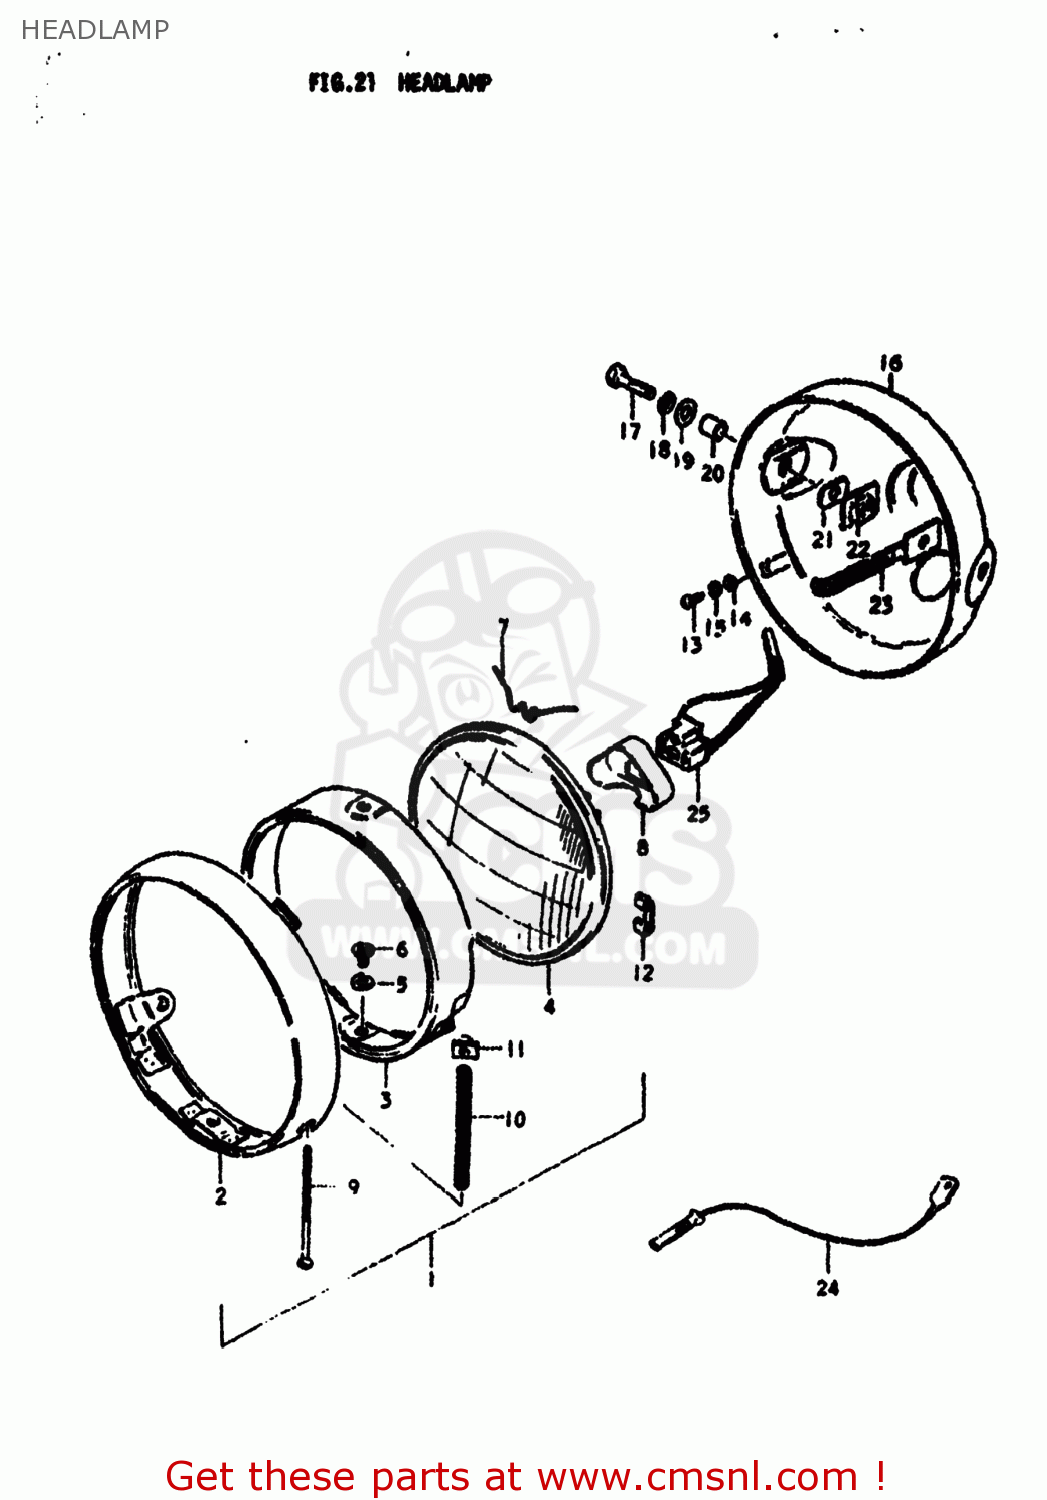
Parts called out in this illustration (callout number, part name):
1	HEADLAMP ASSEMBLY
2	RIM,HEADLAMP
3	RETAINER
4	LAMP UNIT
5	LOCK WASHER
6	SCREW
7	SPRING,HEAD LAMP UNIT
8	COVER
9	SCREW
10	SPRING,HEADLAMP ADJUST
11	NUT
12	COVER, FITING
13	SCREW
14	WASHER
15	LOCK WASHER
16	HOUSING,HEADLAMP
17	BOLT
18	LOCK WASHER
19	WASHER
20	SPACER (8.6X13.8X9)
21	CUSHION
22	PLATE,HEADLAMP HOUSING
23	PLATE,HEADLAMP HOUSING
24	WIRE,WIRING HARNESS LEAD
25	LEAD WIRE,HEADLAMP
